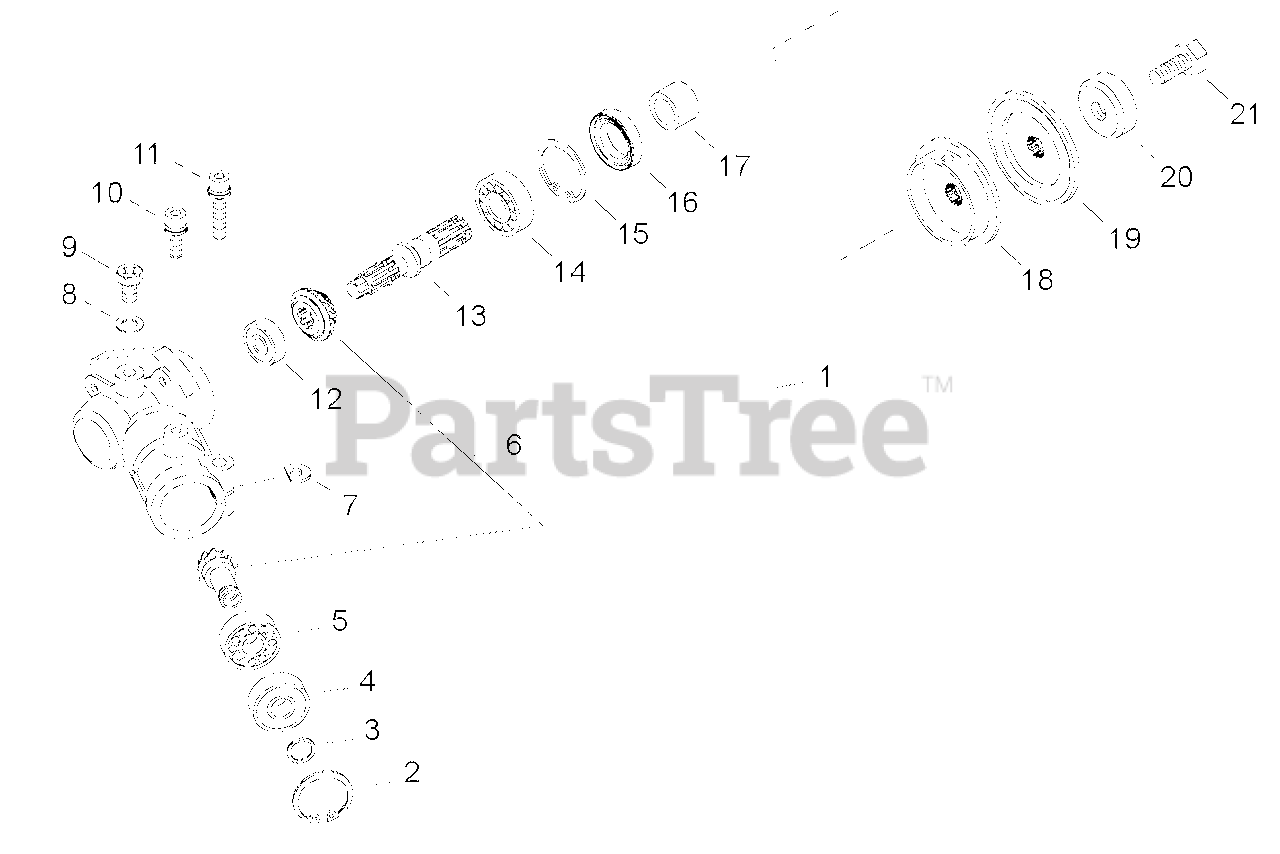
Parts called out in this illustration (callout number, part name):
1	GEAR CASE ASSY
2	RING, RETAINING - 24
3	RING, RETAINING
4	BEARING, BALL - 609ZZ
5	BEARING, BALL - 609
6	GEAR SET
7	SHIM
8	WASHER - 6
9	BOLT - 6X10
10	SCREW - 5X16
11	SCREW - 5X25
12	BEARING, BALL - 608DDU
13	GEAR - SHAFT
14	BEARING, BALL - 6001
15	RING, RETAINING - 28
16	SEAL, OIL
17	SPACER
18	HOLDER (A)
19	ADAPTOR, BLADE - LOWER
20	GUARD
21	BOLT - 8
